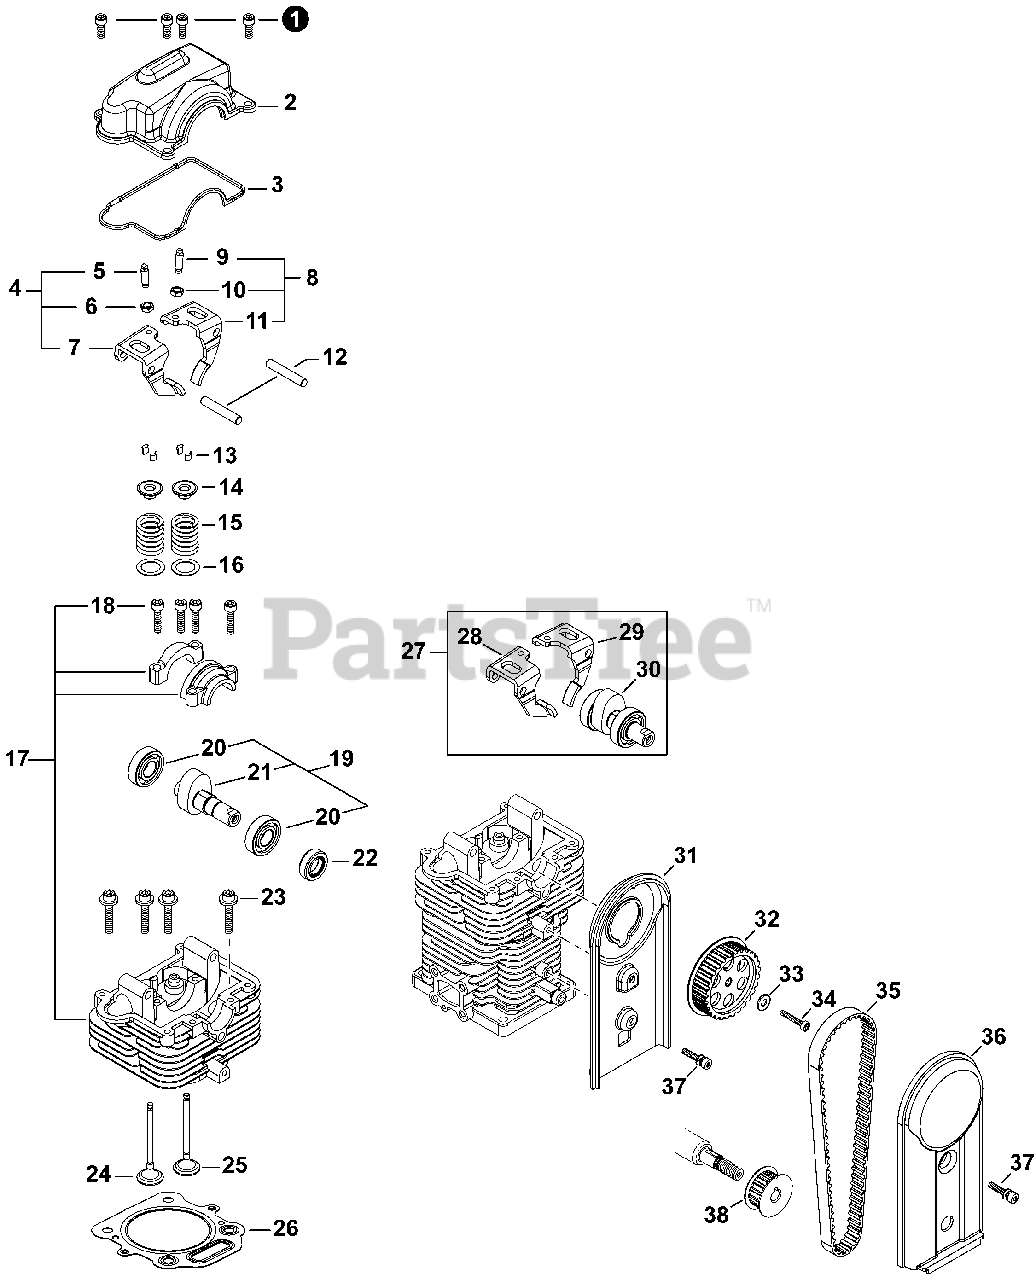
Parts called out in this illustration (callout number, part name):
1	BOLT 5×16
2	COVER, VALVE
3	GASKET, VALVE COVER
4	CAM FOLLOWER ASSY, LEFT
5	SCREW, ADJUSTER
6	NUT, ADJUSTER LOCK 5
7	FOLLOWER, CAM LEFT
8	CAM FOLLOWER ASSY, RIGHT
9	SCREW, ADJUSTER
10	NUT, ADJUSTER LOCK 5
11	FOLLOWER, CAM RIGHT
12	SHAFT, CAM FOLLOWER 6
13	KEEPER, VALVE
14	RETAINER, VALVE
15	SPRING, VALVE
16	WASHER, VALVE 13
17	HEAD ASSY, CYLINDER
18	BOLT M5×22
19	CAMSHAFT ASSY
20	BEARING, BALL 6001
21	CAMSHAFT
22	SEAL, OIL 12
23	BOLT, FLANGE M6×35
24	VALVE, INTAKE
25	VALVE, EXHAUST
26	GASKET, CYLINDER HEAD
27	CAM KIT
28	FOLLOWER, CAM LEFT
29	FOLLOWER, CAM RIGHT
30	CAMSHAFT ASSY
31	CASE, BELT
32	PULLEY, CAM
33	WASHER 5.5×12×0.8
34	BOLT 5×14
36	COVER, BELT
37	BOLT M5×12
38	PULLEY, CRANK
